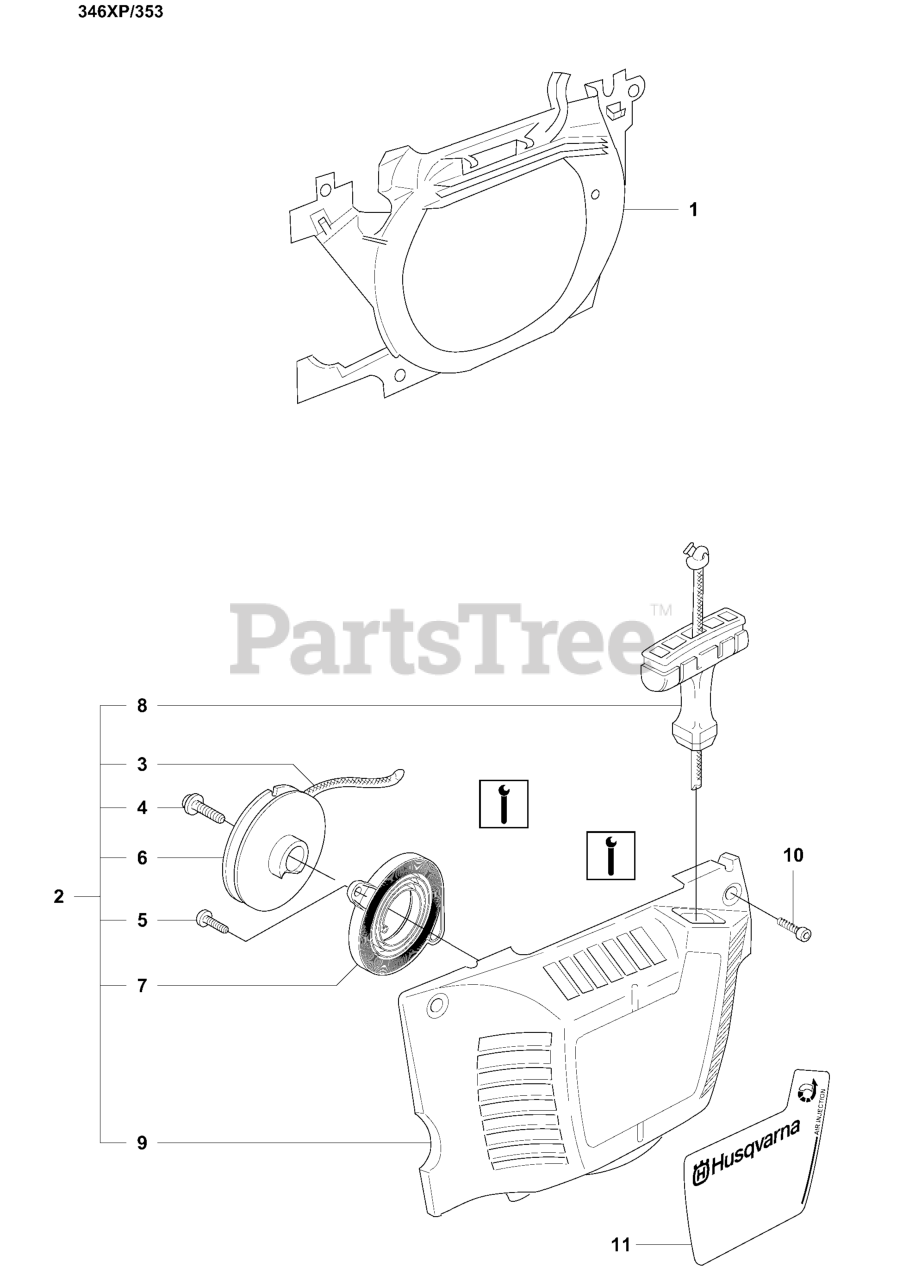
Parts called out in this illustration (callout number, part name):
1	AIR CONDUCTOR
2	STARTER HOUSING ASSY.
3	STARTER ROPE
6	PULLEY
7	RETURN SPRING
8	STARTER HANDLE
9	STARTER HOUSING
10	SCREW.CCRPANMO.M5X19 10.9 TBO
11	DECAL
